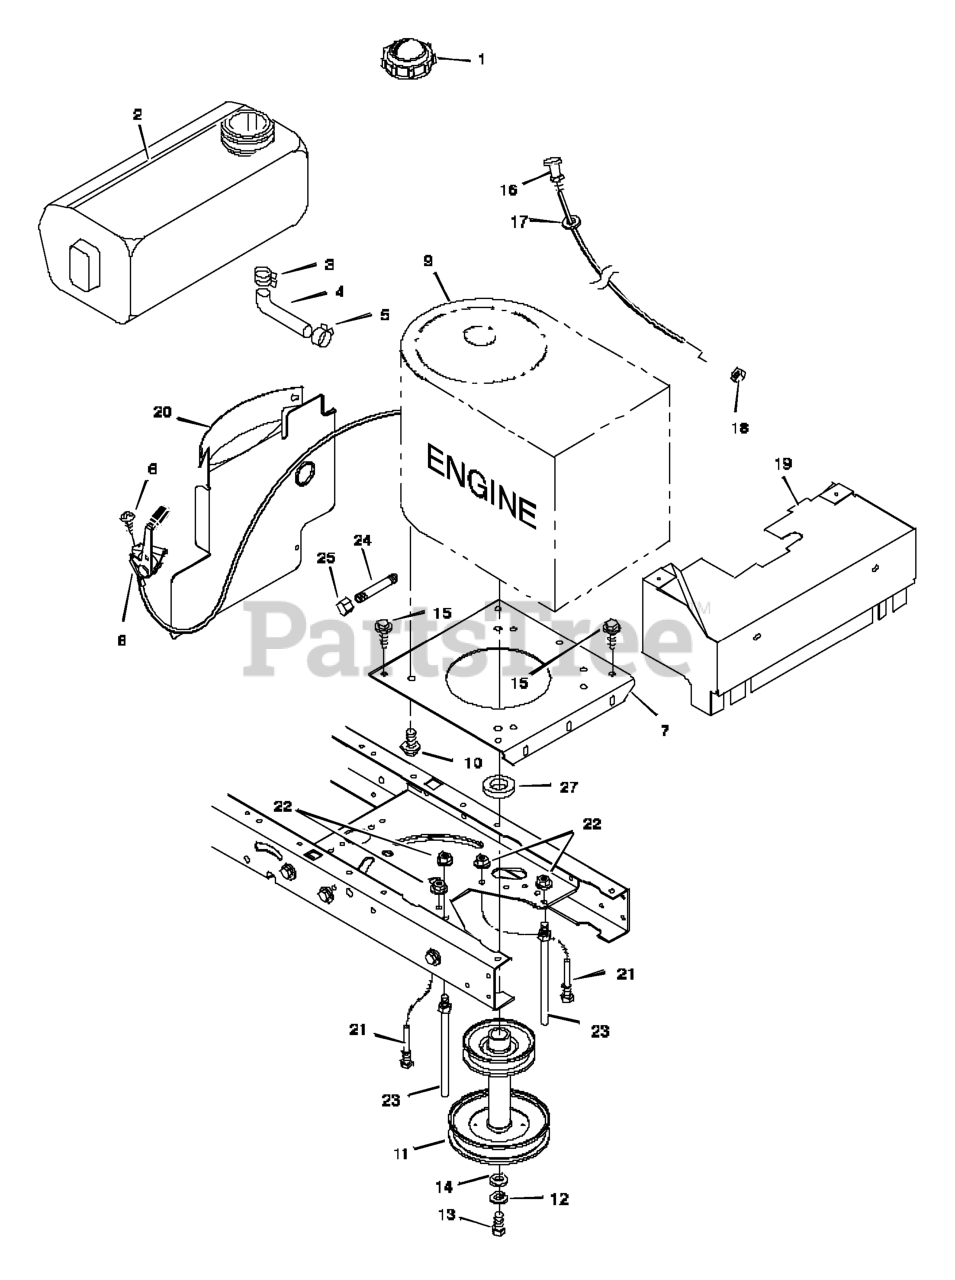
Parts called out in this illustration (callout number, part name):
1	Fuel Cap
2	Fuel Tank
3	Hose Clamp
4	Fuel Line
5	Hose Clamp
7	Plate, Engine
8	Throttle Control
9	Engine *
10	Bolt, Engine Mount
11	Stack Pulley Assembly
12	Lockwasher
13	Bolt, Hex
17	Washer
19	Baffle, Front Engine
20	Baffle, Rear Engine
21	Guide, Belt
22	Nut, Flange
23	Guide, Belt
24	Pipe, Oil Drain
25	Cap, Oil Drain
